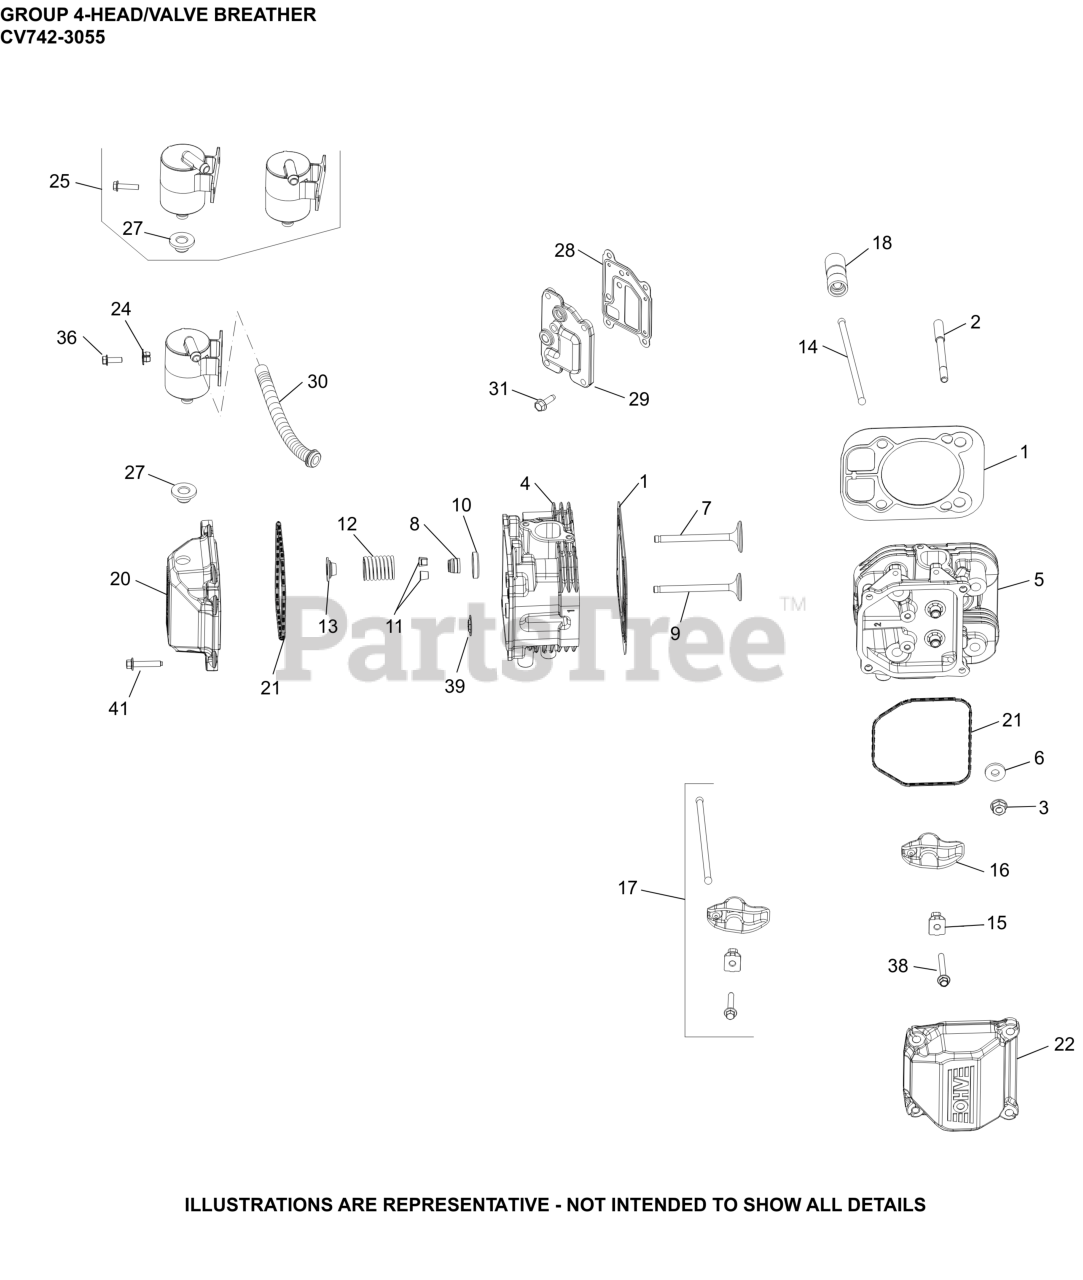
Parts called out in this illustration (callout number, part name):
1	KIT, GASKET CYLINDER HEAD
2	STUD, M8X1.25
3	NUT, FLG M8X1.25
4	KIT, CYLINDER HEAD (#1)-(#2481803S)
5	KIT, CYLINDER HEAD (#2)-(#2481804S)
6	WASHER, FLAT 8.6 MM
7	VALVE, INTAKE (STD)
7	VALVE, INTAKE (.25)-(#DSC)
8	SEAL, VALVE BAND
9	VALVE, EXHAUST
9	VALVE, EXHAUST (.25)
10	RETAINER, SPRING
11	KIT, RETAINER
12	SPRING, VALVE
13	CAP, VALVE SPRING
14	ROD, PUSH
15	PIVOT, ROCKER ARM
16	ARM, ROCKER
17	KIT, VALVE TRAIN
18	LIFTER, VALVE HYDRAULIC-USE 25 351 11-S
20	KIT, VALVE COVER
21	O-RING (YELLOW), VALVE CO
22	KIT, VALVE COVER-PLAIN (PLASTIC)
24	NUT, PLASTIC
25	KIT, BREATHER SEPARATOR
27	GROMMET, RUBBER
28	GASKET, BREATHER
29	KIT, BREATHER COVER-(#2403303S)
30	HOSE, BREATHER VERTICAL HDAC
31	SCREW, THREAD FORMING
36	SCREW, HI-LOW
38	SCREW, HEX FLANGE
39	RETAINER, VALVE GUIDE (KM)
41	SCREW, HEX FLANGE (M6 X 31.625 DOG PT)
